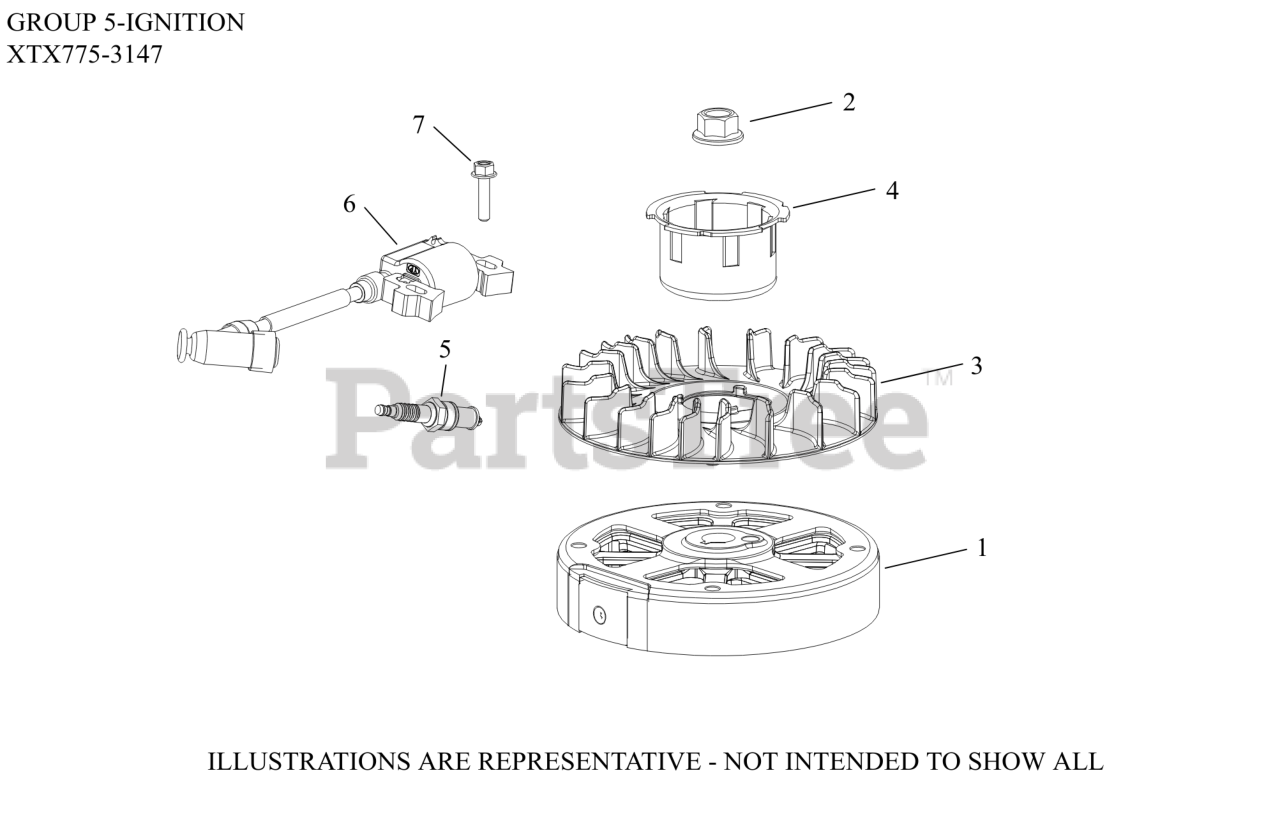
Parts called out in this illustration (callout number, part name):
1	FLYWHEEL ASSEMBLY
2	NUT, FLYWHEEL (W/SERRATIONS)
3	FAN, FLYWHEEL
4	CUP, STARTER DRIVE
5	PLUG SPARK 12MM RFI
6	MODULE IGN (#1458416S)
7	SCREW, M6 X 25-(#25086436S)
